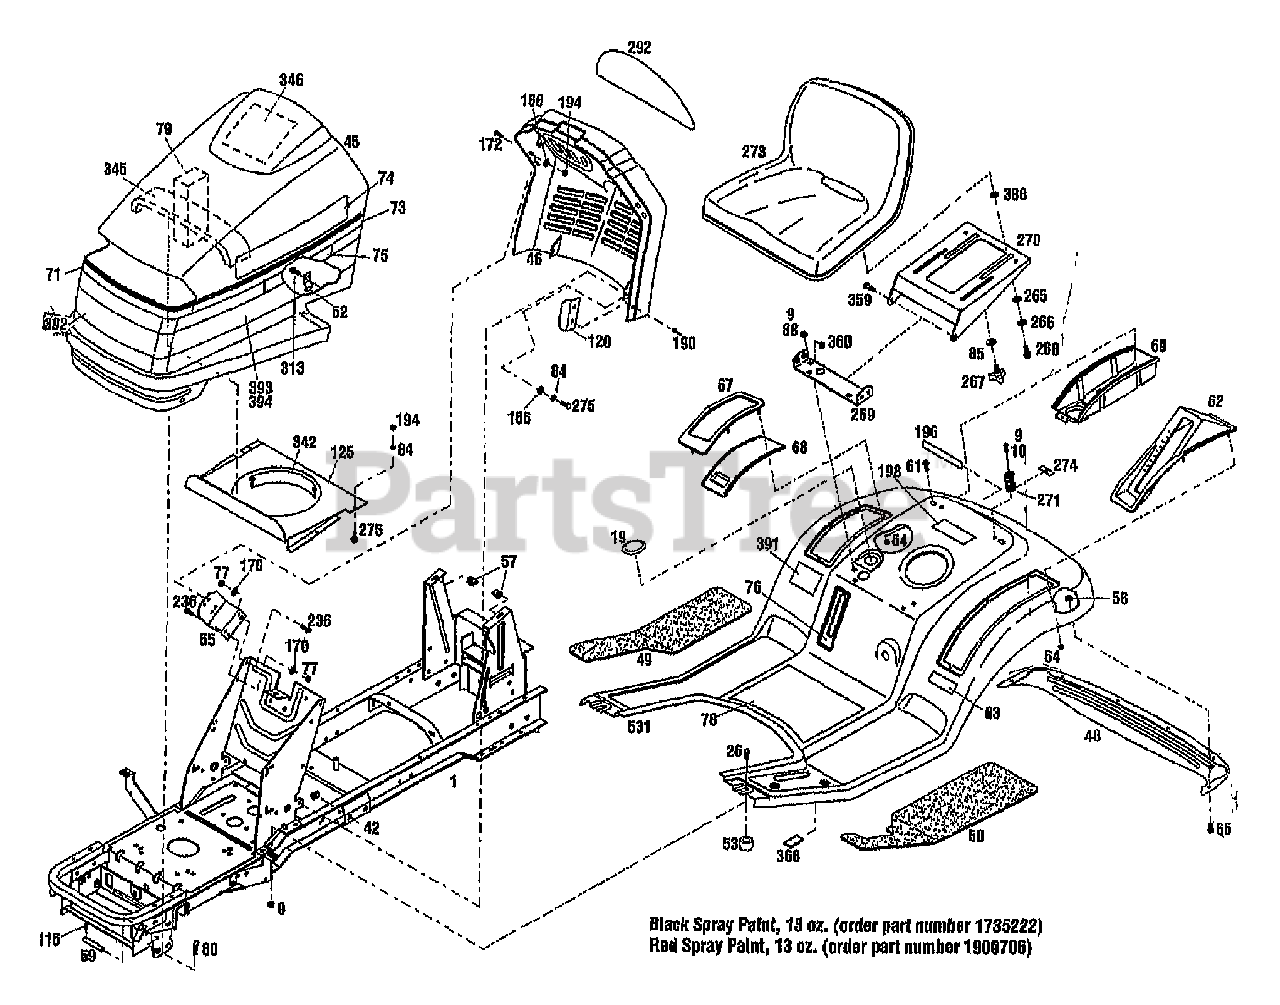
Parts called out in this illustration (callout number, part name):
1	ASSM-FRAME {13078}
1	ASSM-FRAME LTX {13079}
9	NUT-HFLK 5/16-18 ZP
10	SCR-HHC 5/16-18X.75 GR 5 ZP
19	PLUG 2.50 {13079}
26	SCR-CARR 5/16-18X1.0 G2 ZP
42	NUT-SPEED
45	HOOD-TRACTOR
46	CONSOLE
48	TRIM-FENDER REAR
49	PAD-FOOT RH
50	PAD-FOOT LH
52	LATCH
53	SPACER-TUBULAR
55	BRKT-MOUNTING
56	NUT-HF/LK 1/4-20 ZP
57	NUT-SELF RETAIN 5/16-18
59	PIN-PIVOT HOOD
60	PIN-HITCH .125X2.56 ZP
61	SCR-LOCK
62	COVER-LIFT HANDLE
63	DECAL-AMERICAN LEGEND-LRG
64	NUT-SELF THREADING
65	SCR-HH 1/4-20X.625
67	TOP-STORAGE COVER
68	COVER-CONTAINER
69	CONTAINER-STORAGE
71	DECAL-STRIPE HOOD FRONT
73	DECAL-STRIPE SIDE
74	DECAL-LOGO TROY-BILT
75	DECAL-MODEL 13039 {13078}
75	DECAL-MODEL 13036 {13079}
76	DECAL-FUEL LEVEL
77	NUT-HEX 5/16-18 ZP
78	DECAL-OPER INST
79	BLOCK-SEALING {13078}
84	WASHER-LK .25 ZP
85	WASHER-FLAT 3/8 SAE
88	SCR-CARR 5/16-18X.62 G2 ZP
115	PIN-ROLL .188X1.0
120	BRKT-HOOD ALIGN
125	SHIELD-HEAT UPPER
166	WASHER-FLAT 1.25X.28X.062 ZP
170	WASHER-LK .312 ZP
190	RIVET-POP
194	NUT-HEX 1/4-20 ZP
196	DECAL-LOGO FENDER
198	DECAL-FUEL
236	SCR-HFLK 5/16-18X.75 ZP
265	WASHER-1.06X.51X.09 NYLON
266	WASHER-BOW .74X.52X.01
268	SCR-SHLDR 3/8-16X.25 G5ZP
269	BRKT-SUPPORT SEAT
270	SUPPORT-SEAT
271	SPRING-COMPRESSION
273	KIT-SEAT (TRACTOR)
274	BRKT-SPRING HOLD DOWN
275	SCR-HH 1/4-20X.625 G5 ZP
292	LENS-INSTRMTS WARN LIGHTS
342	GASKET-HEAT SHIELD
345	STRIP-SEALING
346	DECAL-SERVICE
359	SCR-HH 3/8-16X.88 G5 ZP
360	NUT-H/LK 3/8-16
388	WASHER-FLAT
391	DECAL-LOGO WORLD CUP
392	DECAL-LOGO WORLD CUP FRONT
393	DECAL-LOGO WORLD CUP LH
394	DECAL-LOGO WORLD CUP RH
531	FENDER-RED W/DECALS
